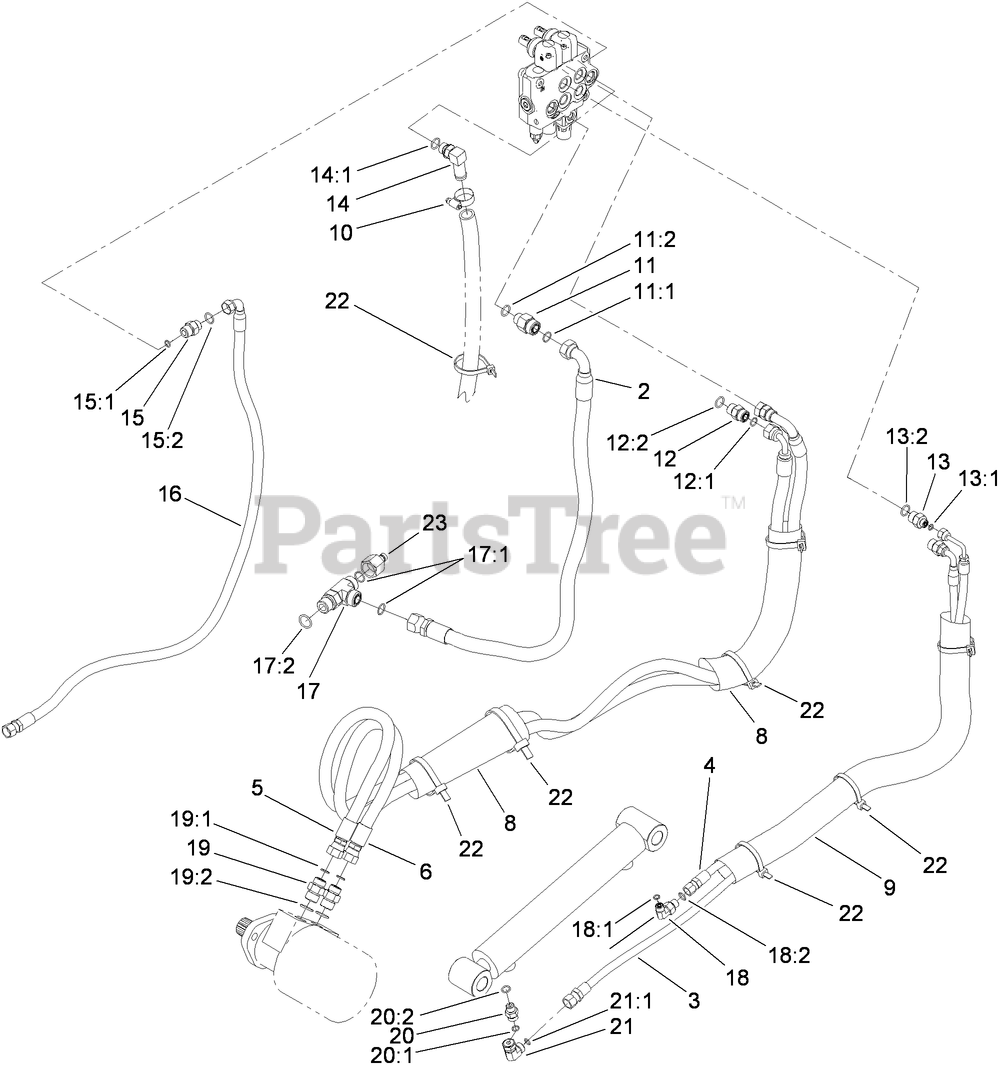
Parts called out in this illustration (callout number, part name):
2	HOSE-HYD
3	HOSE-HYD
4	HOSE-HYD
5	HOSE-HYD
6	HOSE-HYD
8	SLEEVE-PROTECTIVE
9	SLEEVE-PROTECTIVE
10	CLAMP-HOSE
11	FITTING-STR
11:1	O-RING
11:2	O-RING
12	FITTING-STRAIGHT
12:1	O-RING
12:2	O-RING
13	FITTING-STR
13:1	O-RING
13:2	O-RING
14	FITTING-ELB 90
14:1	O-RING
15	FITTING-STRAIGHT
15:1	O-RING
15:2	O-RING
16	HOSE-HYD
17	FITTING-TEE
17:1	O-RING
17:2	O-RING
18	FITTING-ELBOW 90
18:1	O-RING
18:2	O-RING
19	FITTING-STRAIGHT
19:1	O-RING
19:2	O-RING
20	VALVE-CHECK
20:1	O-RING
20:2	O-RING
21	FITTING-HYD, 90 DEG
21:1	O-RING
22	TIE-CABLE
23	NIPPLE
